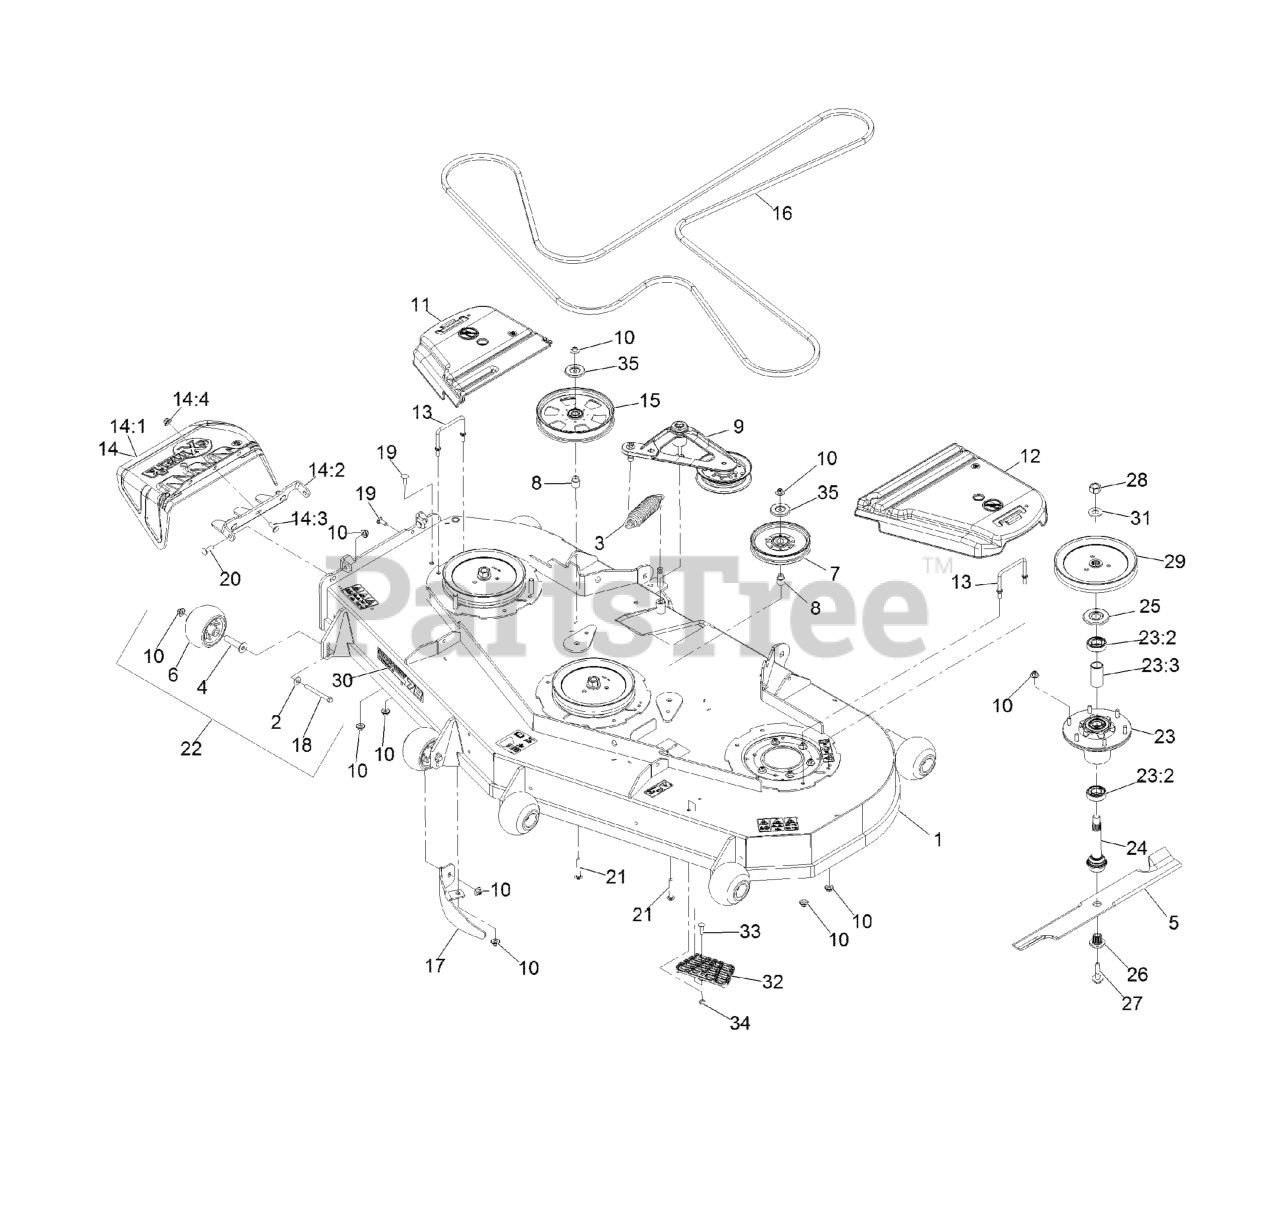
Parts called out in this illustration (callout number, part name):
1	ASM,DECK W/DECALS 724
2	WASHER-BELLEVILLE
3	SPRING-EXTENSION
4	AXLE, ROLLER
6	ROLLER-SCALP, ANTI
7	IDLER-PULLEY
8	BUSHING-IDLER
9	DECK IDLER ASM
10	Nut-Nyloc 3/8-16 Flg
11	COVER-BELT, RH
12	COVER-BELT, LH
13	WIREFORM-COVER
14	ASM,DISCHARGE CHUTE
14:1	CHUTE,DISCHARGE
14:2	BRACKET,DISCHARGE CHUTE
14:3	SCREW-CARR
14:4	Nut-Nyloc 3/8-16 Flg
15	PULLEY-IDLER, FLAT
17	BAFFLE-DOGLEG, LZ72
18	SCREW-HH 3/8-16 X 3 3/4 GR 8
19	SCREW-CARR
20	Bolt-Carriage 3/8-16 X 1 1/4
21	SCREW-CARR
22	KIT, ANTI-SCALP ROLLER
23	ASM-CUTTER HSG WITH BEARINGS
23:2	BEARING-BALL
23:3	SPACER-BEARING
24	ASM-SPINDLE AND SEAL
25	GUARD,BEARING TOP .989
26	BUSHING,SPLINED
27	SCREW,SEMS 1/2-20 X 2.19
28	NUT-HEX
29	SHEAVE,BLADE DRIVE 8.74
30	DECAL, 724
32	STEP-DECK
33	Bolt-Carriage 5/16-18 X 1 1/4
34	NUT-HF, NI
35	SHIELD-DUST
